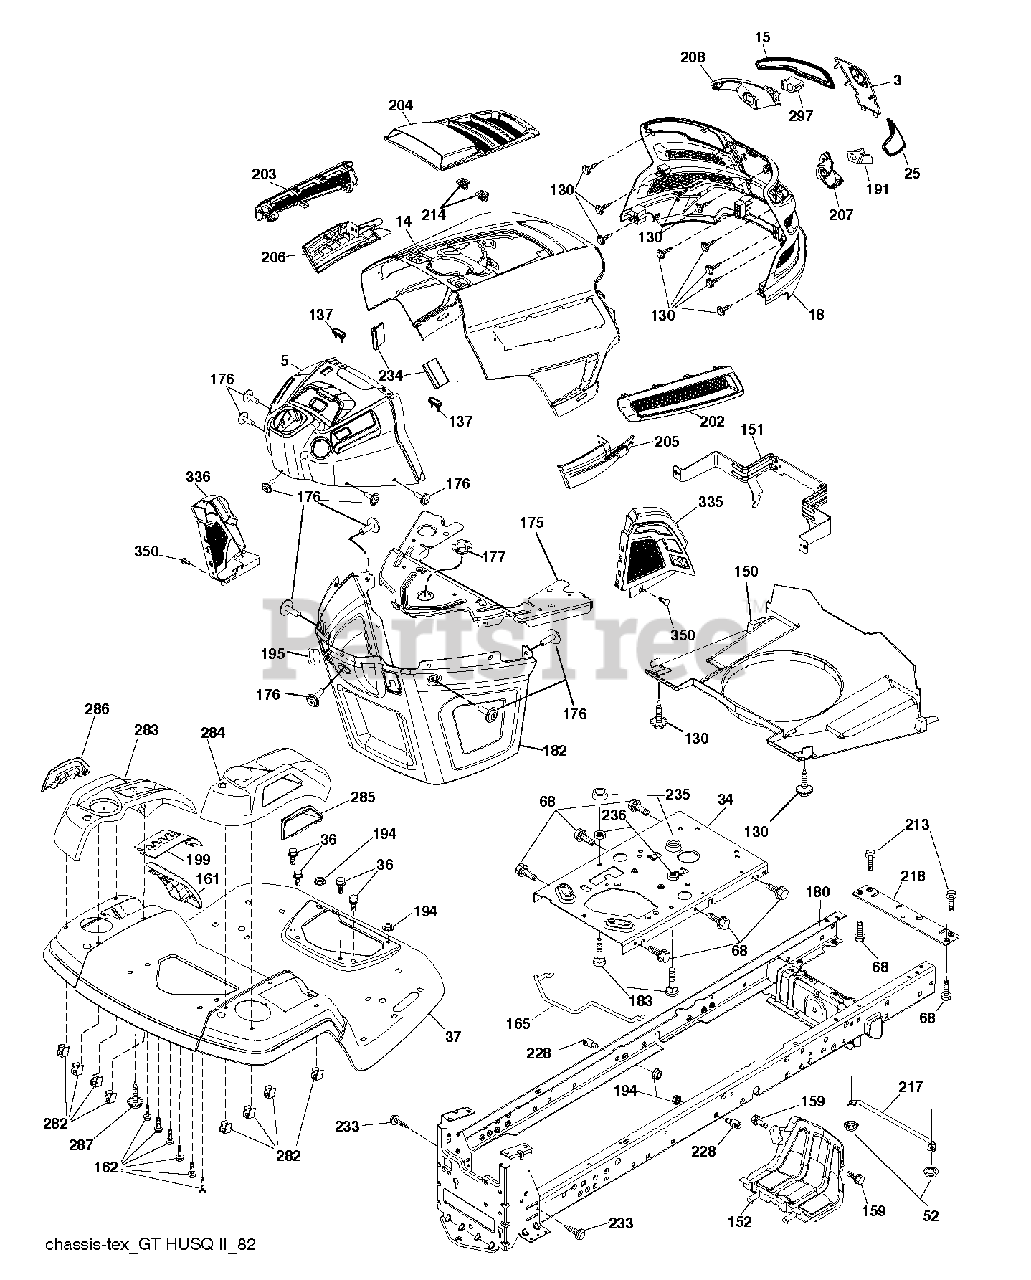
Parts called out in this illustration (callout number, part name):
3	APPLIQUE.SUBASM.GT.HUSQ.II
5	DASH
14	HOOD.ASM.HUSQVARNA.GT.TEX.ORAN
15	LENS.HEADLIGHT.LH.GTII.2011
18	GRILLE.SUBSTRATE.2011.
25	LENS.HEADLIGHT.RH.GTII.2011
34	PLATE.ENGINE.WELDED.CHASSIS
36	SCREW 5/16"
37	FENDER.TLT.FS.W/CPH/FW/RSF.668
52	LOCKNUT
68	SCREW LT
130	SCREW.#10 X 0.750.BOS
137	BUMPER DASH
150	AIR.DUCT.GTV.BLACK
151	BRACKET.PIVOT.HOOD.GT.HUSQ.II
152	SHIELD.BROWNING.PNT.GT.V2
159	SCREW, 3/8-16X3/4
161	WINDOW.FUEL.LT.HUSQ.TEX.498
162	SCREW.HI-LO.CONSOLE
165	SUPPORT.TANK.REAR.W/TEX
175	PLATE.CROSSMEMBER.HUSQ
176	SCREW.#10-24X5/8.RN.QU
177	BUSHING, STEERING
180	CHASSIS
182	DASH.LOWER.COMMON.12V.ADAPTOR
183	BOLT.5/16-18X1-1/4 FULL.THREAD
191	INSERT.REFLECTIVE.RH.HUSQ.GTII
194	NUT LOCK HEX FLANGE 5/16-18
195	PLUG.HOLE.DASH.LOWER.12V.BLK
199	PLATE.DECK.LIFT.HUSQ.LT
202	VENT.SIDE.RH.GT.HUSQ.II.
203	VENT.SIDE.LH.GT.HUSQ.II.498
204	VENT.TOP.HUSQ.GT2
205	SIDE.TRIM.RH.GT.HUSQ.II
206	SIDE.TRIM.LH.GT.HUSQ.II.GRAY
207	BEZEL LIGHT.RH.GT.II.MYLAR
208	BEZEL LIGHT.LH.GT.II.MYLAR
213	BOLT
214	CLIP.RETAINER.TINNER.
217	ROD.PIVOT.HOOD
218	X-PIECE.HOOD.STOP.NON/
228	STUD.FASTNER.W/ANTI-ROTATE
233	BOLT.SHOULDER
234	BUMPER.HOOD.TEX.HUSQVARNA
235	SPACER FENDER
236	NUT.CENTERLOCK.5/16-
282	CLIP.RETAINER.CONSOLE.LT.HUSQ
283	CONSOLE.DECK.LIFT.R.SDFL.HUSQ
284	CONCOLE.CNTRL.PDL.HUSQ.LT.498
285	CONSOLE INSERT RH
286	CONSOLE.INSRT.LH.HUSQ.LT.BLACK
287	SCREW 1/4X20
297	INSERT.REFLECTIVE.LH.HUSQ.GTII
335	COVER.LOWER.DASH.RH.BLACK
336	COVER-LH.LOWER.DASH.GT2.BLACK
350	CLIP.X-MAS.TREE
